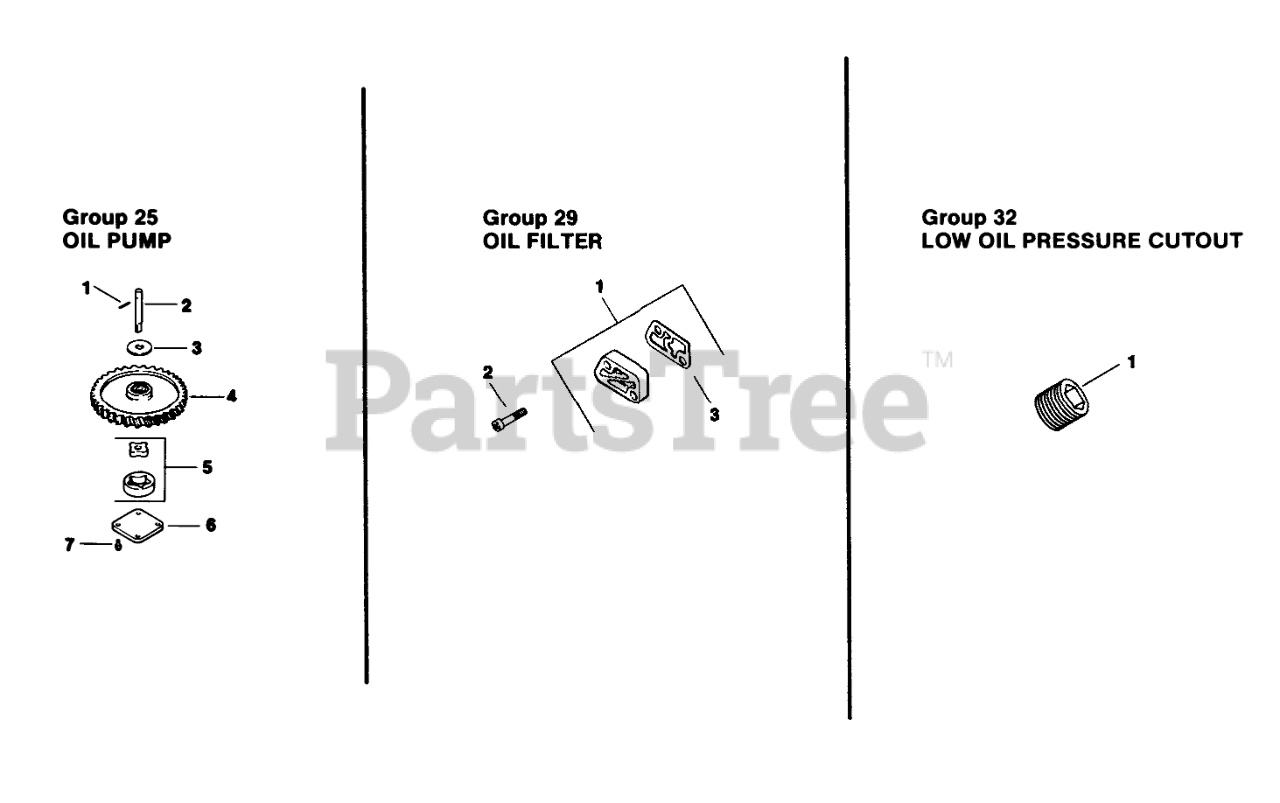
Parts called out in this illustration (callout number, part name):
1	Pin-Roll
1	Kit-Non Filter Cover (Incl. Ref. #3)
1	Plug
2	Shaft-Oil Pump
2	Gasket-Oil Filter
3	Spacer-Shim
3	Screw-H.C.
4	Gear-Oil Pump
5	Rotor Set
6	Cover-Oil Pump
7	Screw
20	Seal-Rear Oil
28	Screw-Hex Washer Hd.
